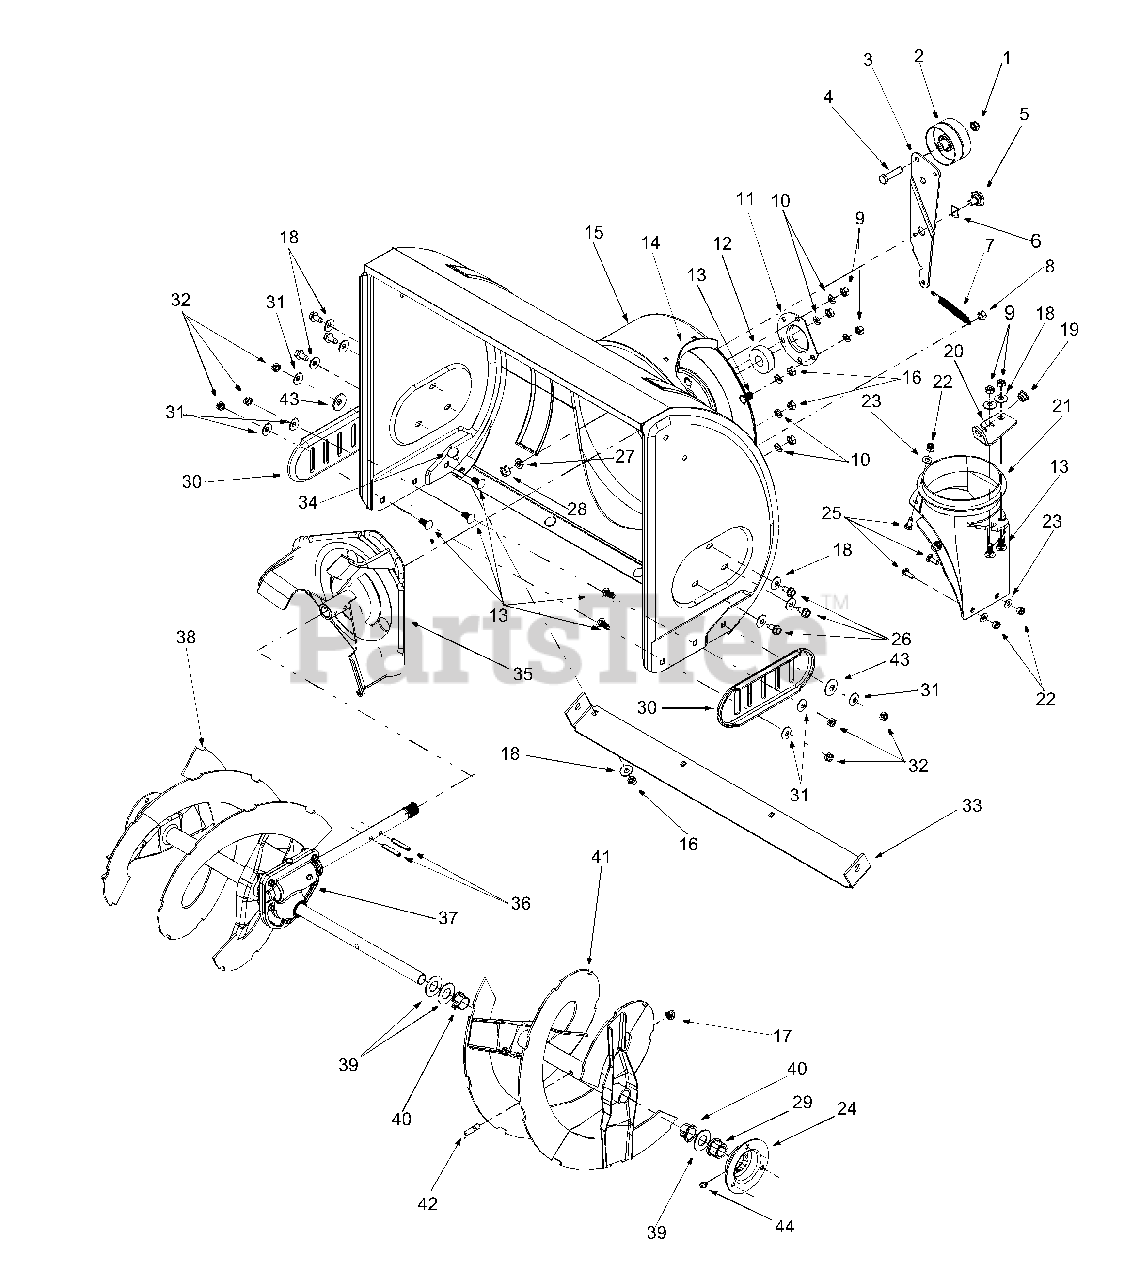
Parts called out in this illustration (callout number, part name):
1	Lock Jam Nut 3/8-24
2	Flat Idler, 2.75 w/o Flanges
4	Hex Cap Screw 3/8-24 x 1.50
5	Shoulder Screw
7	Extension Spring
8	Hex Nut 5/16-18
9	Hex Lock Nut 5/16-18
10	Lock Washer 5/16
11	Bearing Housing, 1.85
12	Ball Bearing, .75 x 1.85
13	Carriage Bolt 5/16-18 x .75
17	Lock Nut 5/16-18
19	Plastic Bushing, .380
21	Chute Adapter, 5.0
22	Hex Lock Nut 1/4-20
24	Bearing Housing w/ Fitting Hole
25	Carriage Screw 1/4-20 x .75
26	Hex Washer Screw 5/16-18
27	Lock Washer 3/8
28	Hex Nut 3/8-16
29	Hex Flange Bearing
32	Hex Nut 5/16-18
34	Carriage Bolt 5/16-18 x .62
36	Spiral Pin, .25 x 1.5
37	24" Gearbox Ass'y w/ Fitting
40	Flange Bushing
42	Shear Bolt 5/16-18 x 1.5
43	Flat Washer, .344 x 1.12 x .87
44	Grease Fitting, 3/16" Drive
